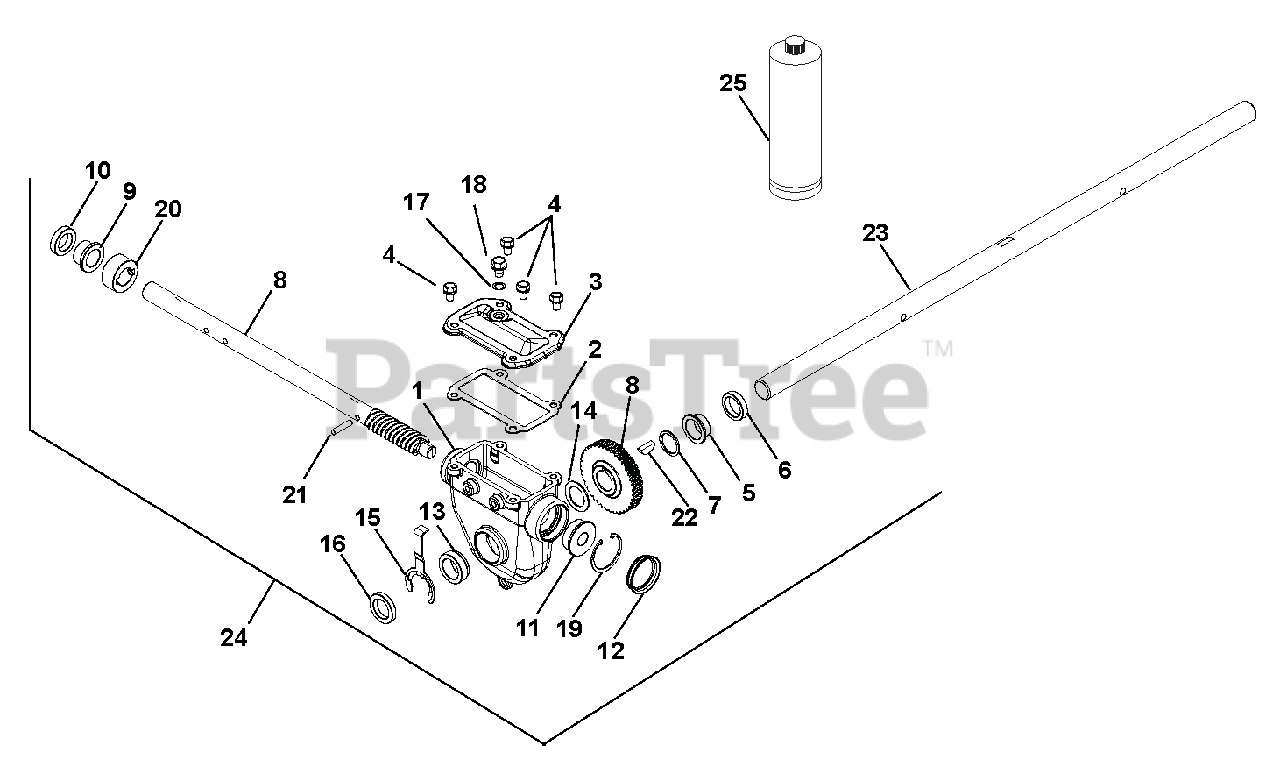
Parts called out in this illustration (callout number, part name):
1	GEARCASE, LARGE MACHINED
2	GASKET, TOP - LARGE GEARCASE
3	COVER, TOP - LARGE IRON
4	BOLT, SEMS .31-18X.50 GR5 YWZC
5	BSHG-FLG 1.006X1.128X.555X1.45
6	SEAL-OIL .999X1.375X.312 TBC29
7	WSHR-FL-STL 1.010X1.505X.062YZ
8	ASSY, WORM SHAFT & GEAR
9	BSHG-FLG .879X1.128X.75X1.45
10	SEAL-OIL .873X1.375X.312 TBC29
11	BSHG-FLG .628X1.503X.58X1.725
12	COVER, GEAR CASE 1.75"
13	BSHG-FLG LARGE, RIGHT
14	WSHR-FL-STL 1.010X1.250X.068YZ
15	BUSHING RETAINER, LARGE
16	SEAL-OIL .999X1.500X.250 TBC29
17	WSHR-FL-ALUM .385X.562X.032
18	@SCR-ROLOK .38-16X.50 HWH YWZC
19	RG-RTNG-INT 1.750X.062
20	THRUST COLLAR, .875"ID SLIPFIT
21	PIN-STR .250X1.12 6150
22	KEY-WDRF .25X.875 HRD #A
23	SHAFT, RAKE-28"
24	GEAR CASE, 28" IRON PRO TOP-LD
25	ARIENS L3 LUBE, 8 OZ BOTTLE
